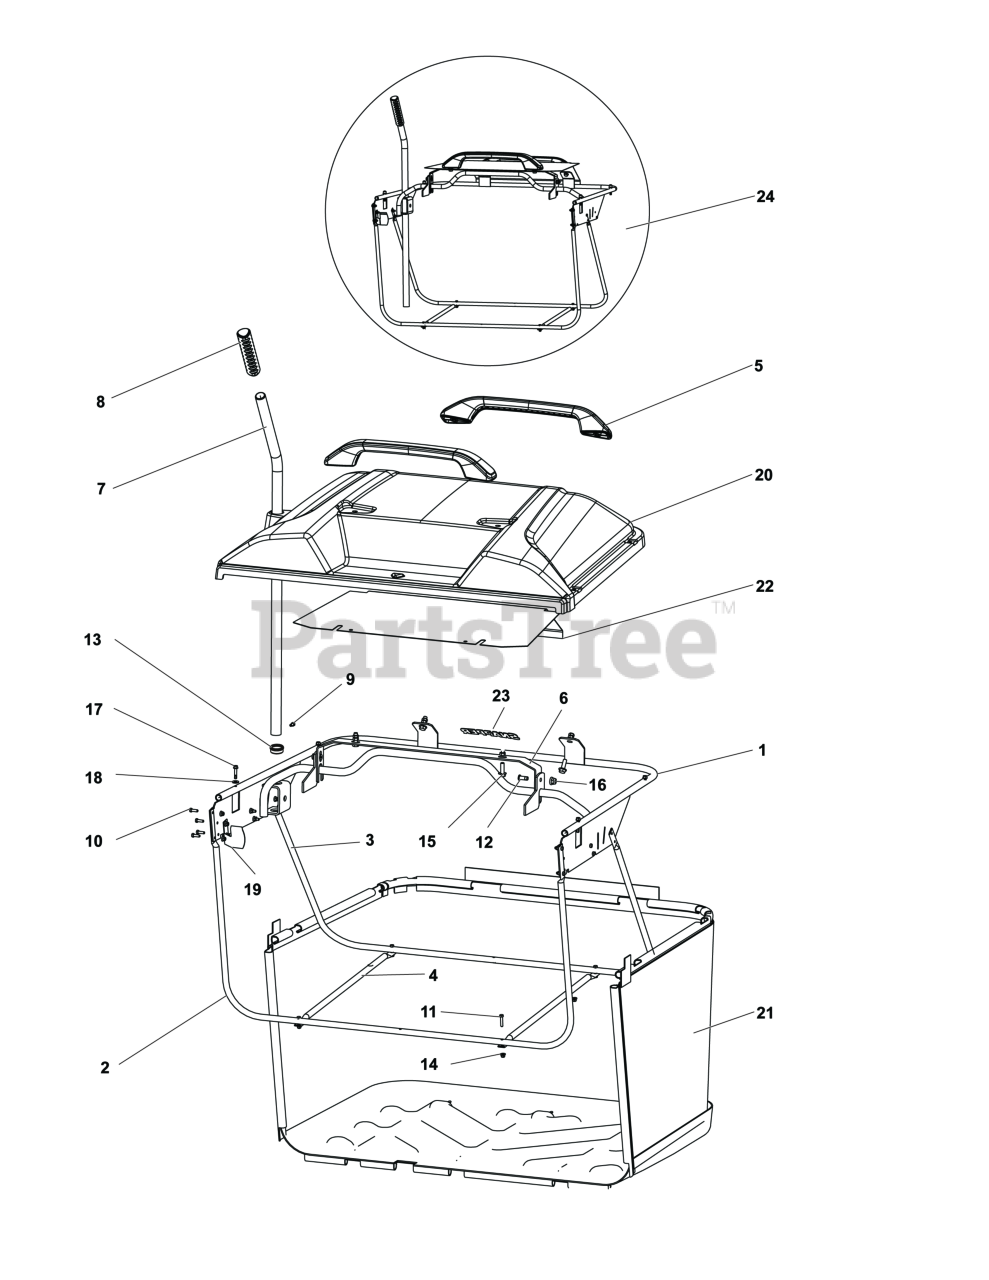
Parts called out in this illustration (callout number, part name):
6	PLATE, Reinforcement
21	COLLECTOR
23	DECAL, Brand
24	CATCHER, GRASS
